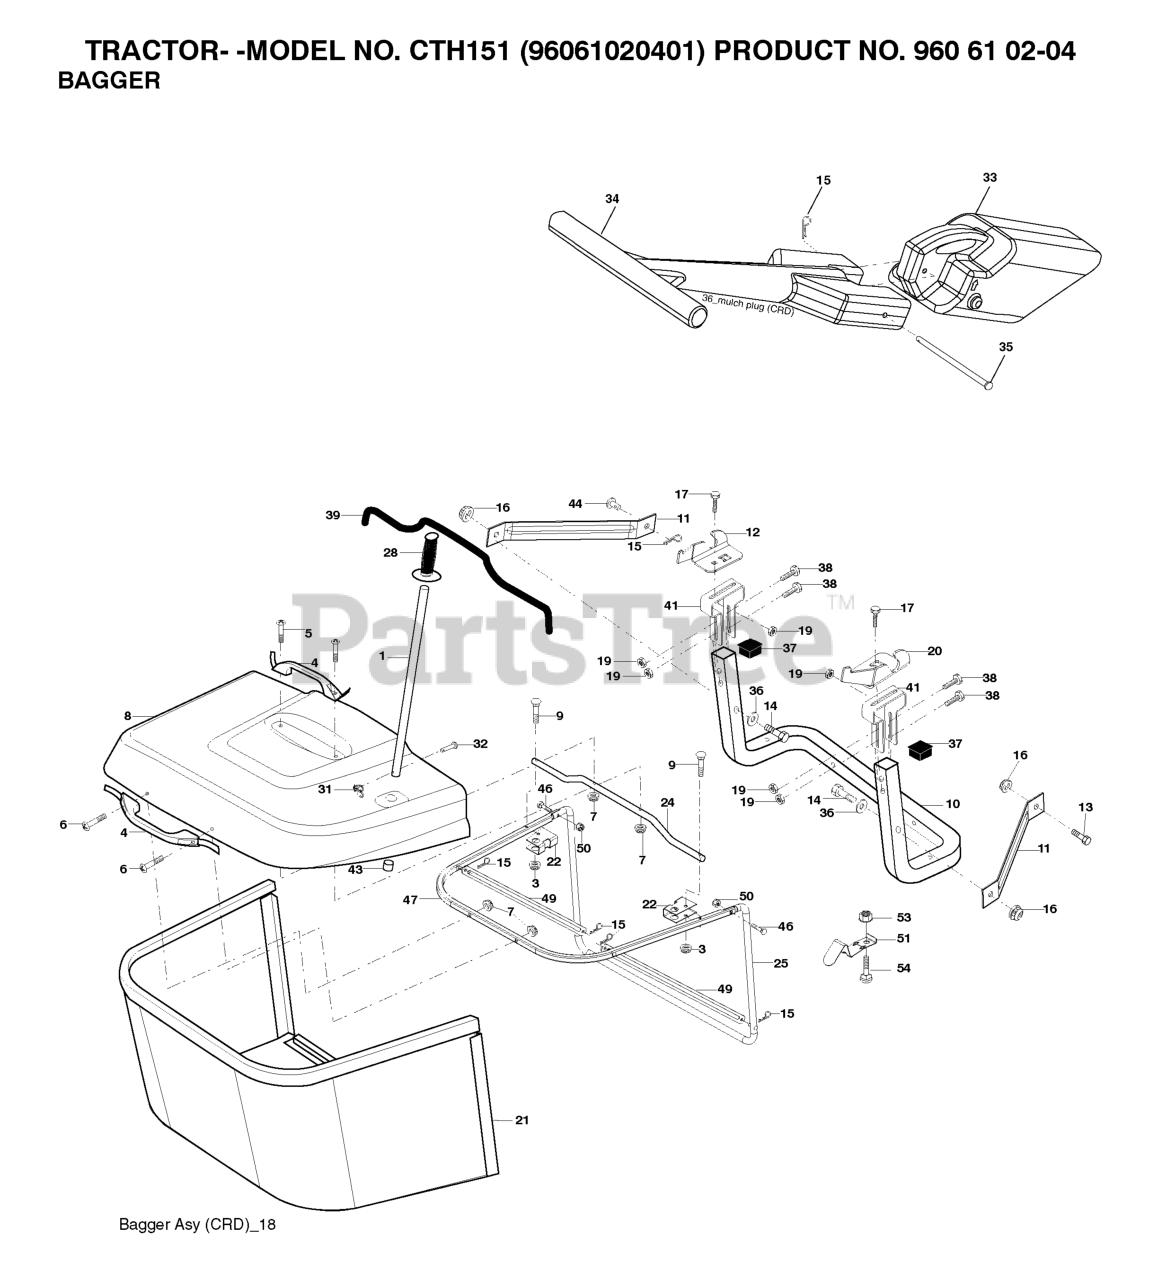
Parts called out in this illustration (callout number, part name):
1	TUBE HANDLE
3	NUT T
4	HANDLE.BAGGER.W/LVRS.BLK.CRD
5	SCREW.PAN.HEAD
6	REPL BY 532 75 00-29
8	COVER.PNT.BGR.CRD.WSLOTS.MS668
9	Bolt Carriage 1/4-20 x 2.25d x Gr.5
10	TUBE
11	BRACKET.SUPPORT.UPPER.BAG.CRD
12	BRKT PIVOT
14	BOLT-HEX EAK
15	RETAINER-SPRNG RB
16	NUT LOCK FLG 3/8-16 UNC
17	RP BOLT 5/16-18 X3/4 ZN/YEL GR
19	NUT LOCK HEX FLANGE 5/16-18
20	BRKT.PIVOT.RH.CRD
21	BAGGER.ASM.CRD.2007
22	BRKT.SIDE.BAG.CRD
24	TUBE.PIVOT.BAG.CRD.BLACK
25	PIPE
28	GRIP.HANDLE.BLACK
31	RETAINER CLIP
32	RIVET,DRILLED
33	PLUG.MULCHER.92 CRD
34	HANDLE.MULCHER.92.CRD (2 2)
36	WASHER
37	Plug Support Bagger CRD
38	BOLT.5/16-18X2.5
39	SEAL.TRIM.37'
41	BRKT.VERT.ADJ.BAGGER.CRD
43	PLUG, TUBING END
46	BOLT.CARRIAGE.5/16-18
47	PIPE
49	ROD
50	NUT.71038.31-18.HEX.NYLOCK
51	LATCH
53	NUT
54	BOLT
